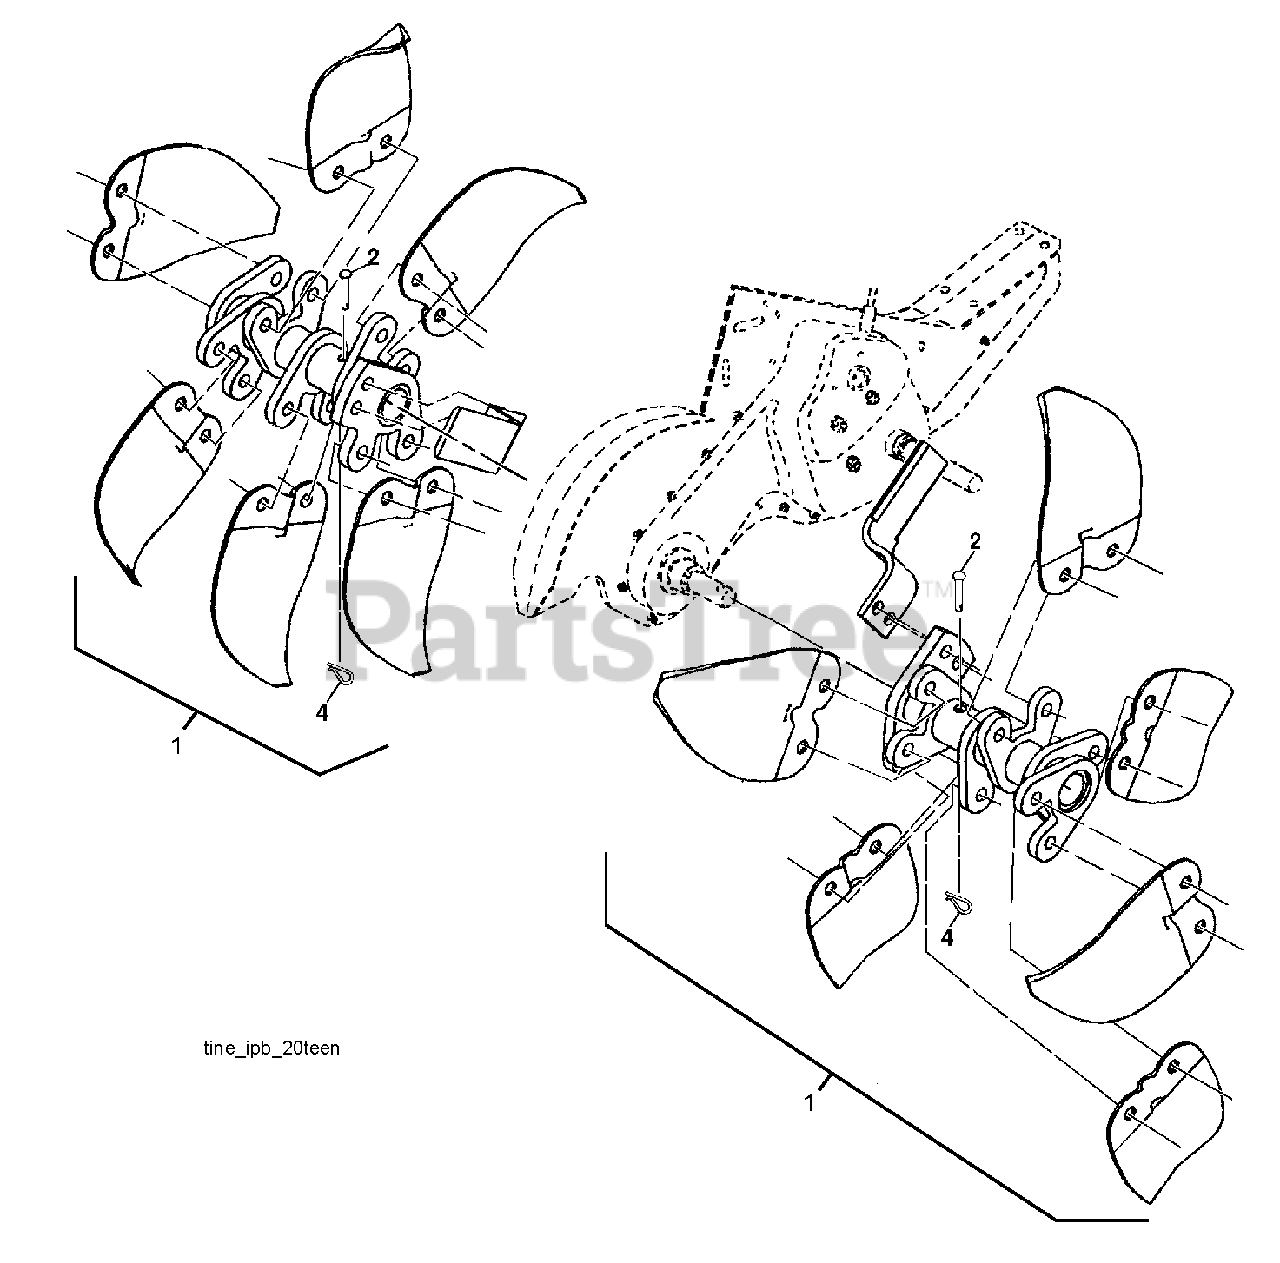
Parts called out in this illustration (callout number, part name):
1	HUB.ASM.DRT17.2004 (CMPL KIT)
2	CLEVIS PIN
4	SPRING RETAINER
